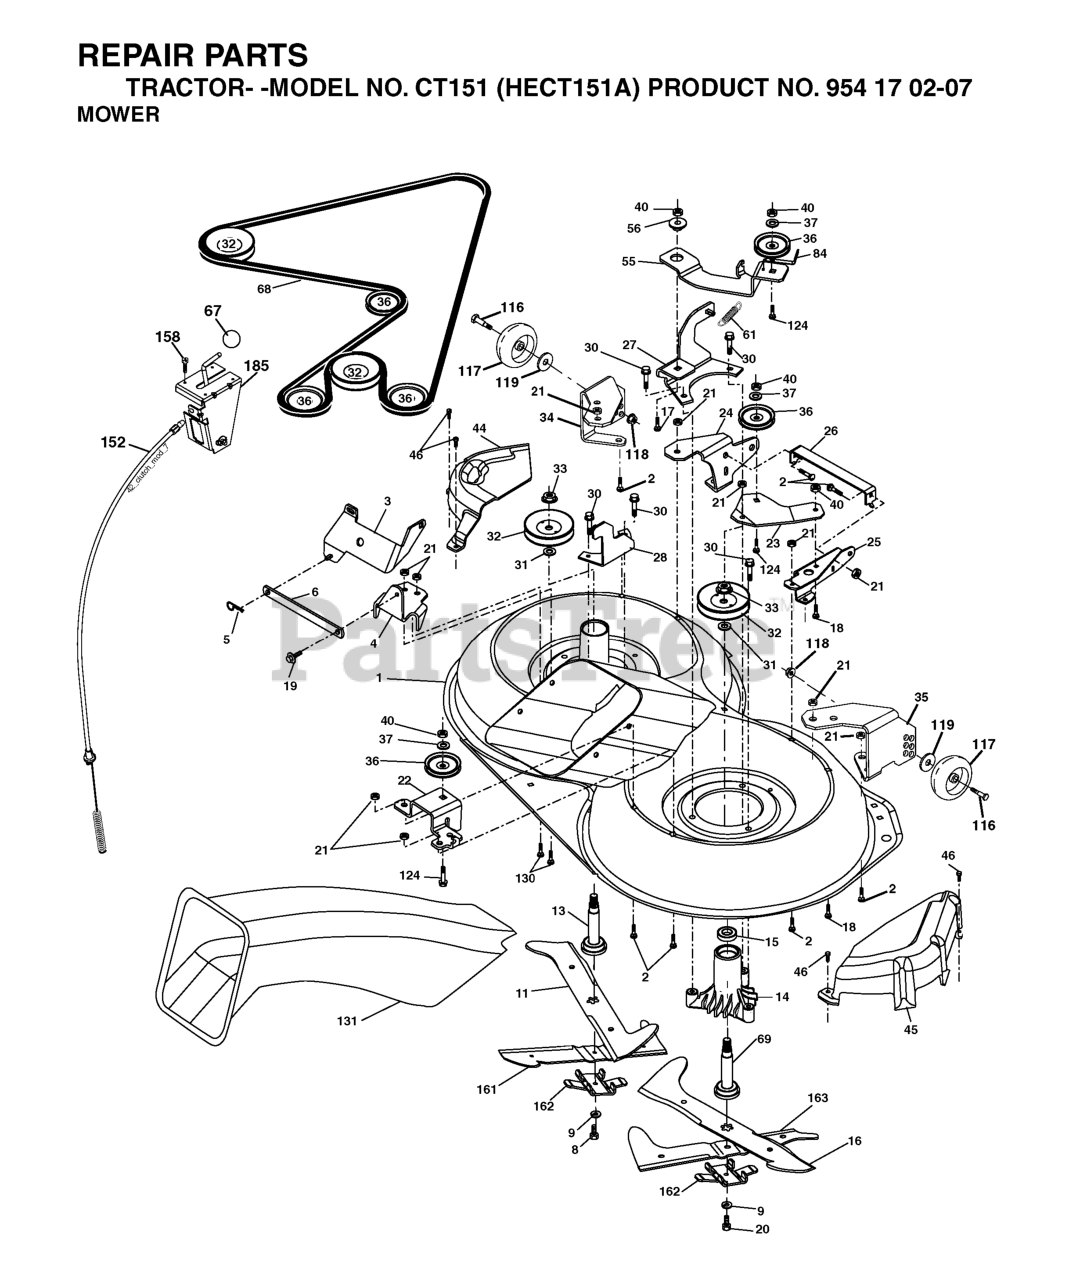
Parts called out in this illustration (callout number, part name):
1	MOWER HOUSING, DECK
2	RP BOLT 5/16-18 X3/4 ZN/YEL GR
5	RETAINER-SPRNG RB
6	BAR.SWAY.92.CRD
8	BOLT.3/8-24X1.25 GR8
9	LOCKWASHER
13	SHAFT ASM VENT
14	HOUSING.MANDREL.VENTED (MACHD)
17	BOLT.3/8-14X1.25
19	BOLT SHD 5/16-18
20	BOLT.3/8-24X1.25GR8. LHTHRD
21	LOCKNUT
26	BRACE.SUPT.SUSP.FRT.CRD
30	SCREW, WASHER HEAD
31	WASHER.SPACER.MANDREL
32	PULLEY, MANDREL
33	NUT, FLG TOPLOCK 9/16"
36	PULLEY.IDLER.4.25
37	WASHER
45	COVER.MANDREL.RH.CRD
46	SCREW.1/4-20X5/8
56	SPACER.RETAINER.MOWER
61	SPRING.TENSION.BELT
67	KNOB T (3/8 HOLE)
68	HEX-BELT
69	SHAFT.ASM.W/LWR.BRG.RH.THREAD
84	KEEPER, BELT IDLER
116	SHOULDER BOLT
117	WHEEL GAGE DONUT
118	LOCKNUT
119	WASHER.5/16.FLAT.STE.STD.
124	BOLT.3/8-16X1.50
130	BOLT.CARR.SQNK.5/16-18UNC.X3/4
131	CHUTE BAGGER
158	SCREW
185	HEAD ASM. CABLE CLUTCH
